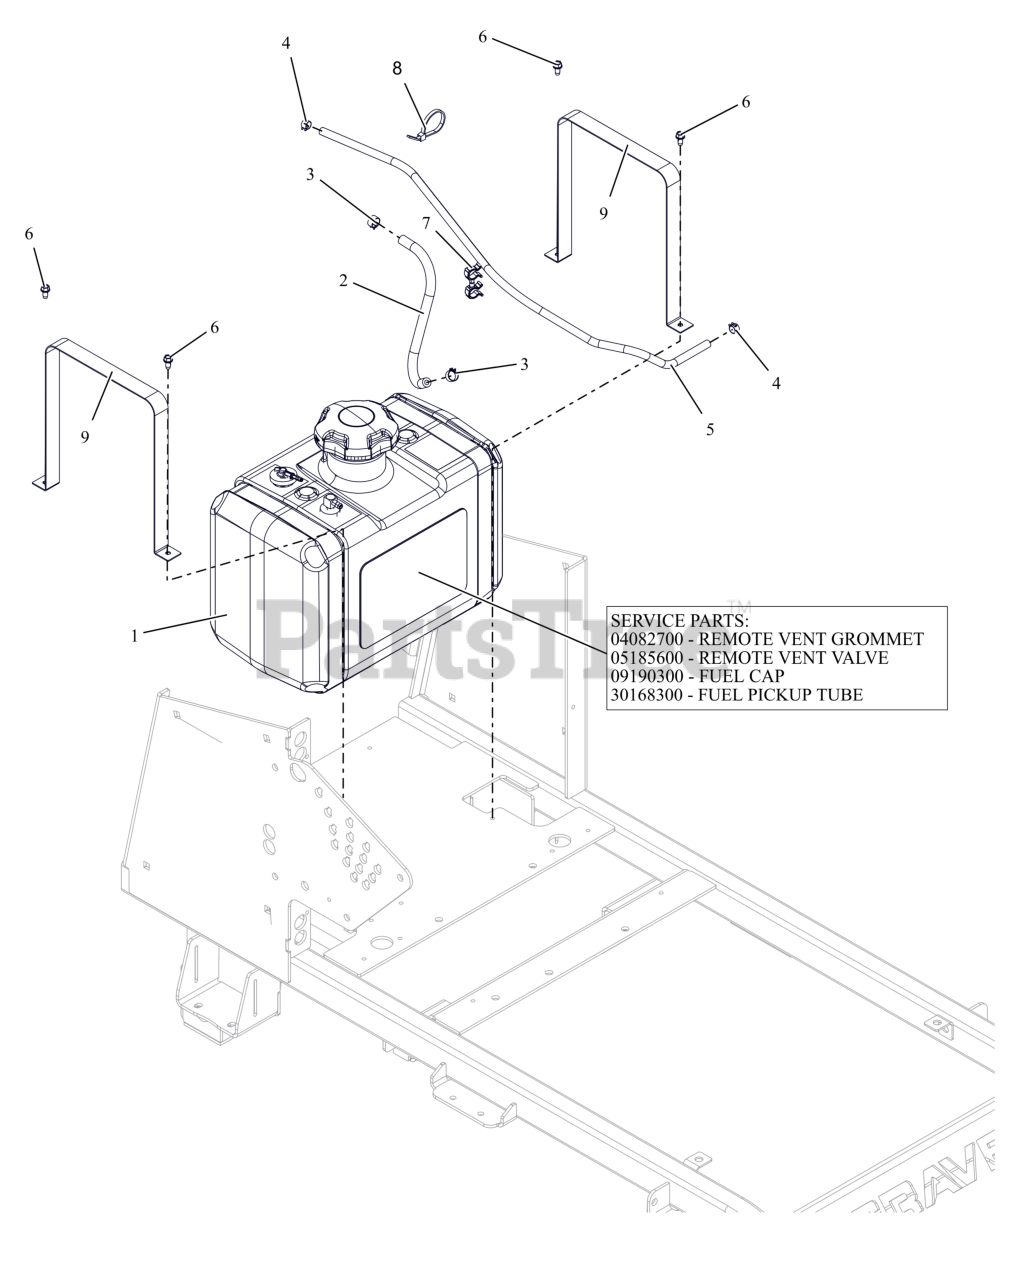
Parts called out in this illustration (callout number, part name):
1	ASM-FUEL TANK 5-GAL(SEMCO)
1	GROMMET, REMOTE VENT NITRILE
1	VALVE, COMBINATION VENT 3/16
1	CAP, FUEL - 3.50 RATCHET INLET VENT
1	FUEL PICKUP TUBE
2	1 INCH OF HOSE, .25 LOW-PERM BULK GAS
3	CLAMP, FUEL LINE
4	CLAMP-HOSE, SPRING .188
5	HOSE, .188 30R7 BULK
6	SCR-TAP .25-20X.50 HWH ZCC
7	CLIP-360DEG SWIVEL.500DIA HOSE
8	CABLE TIE LG 5-1/2
9	STRAP- TANK
